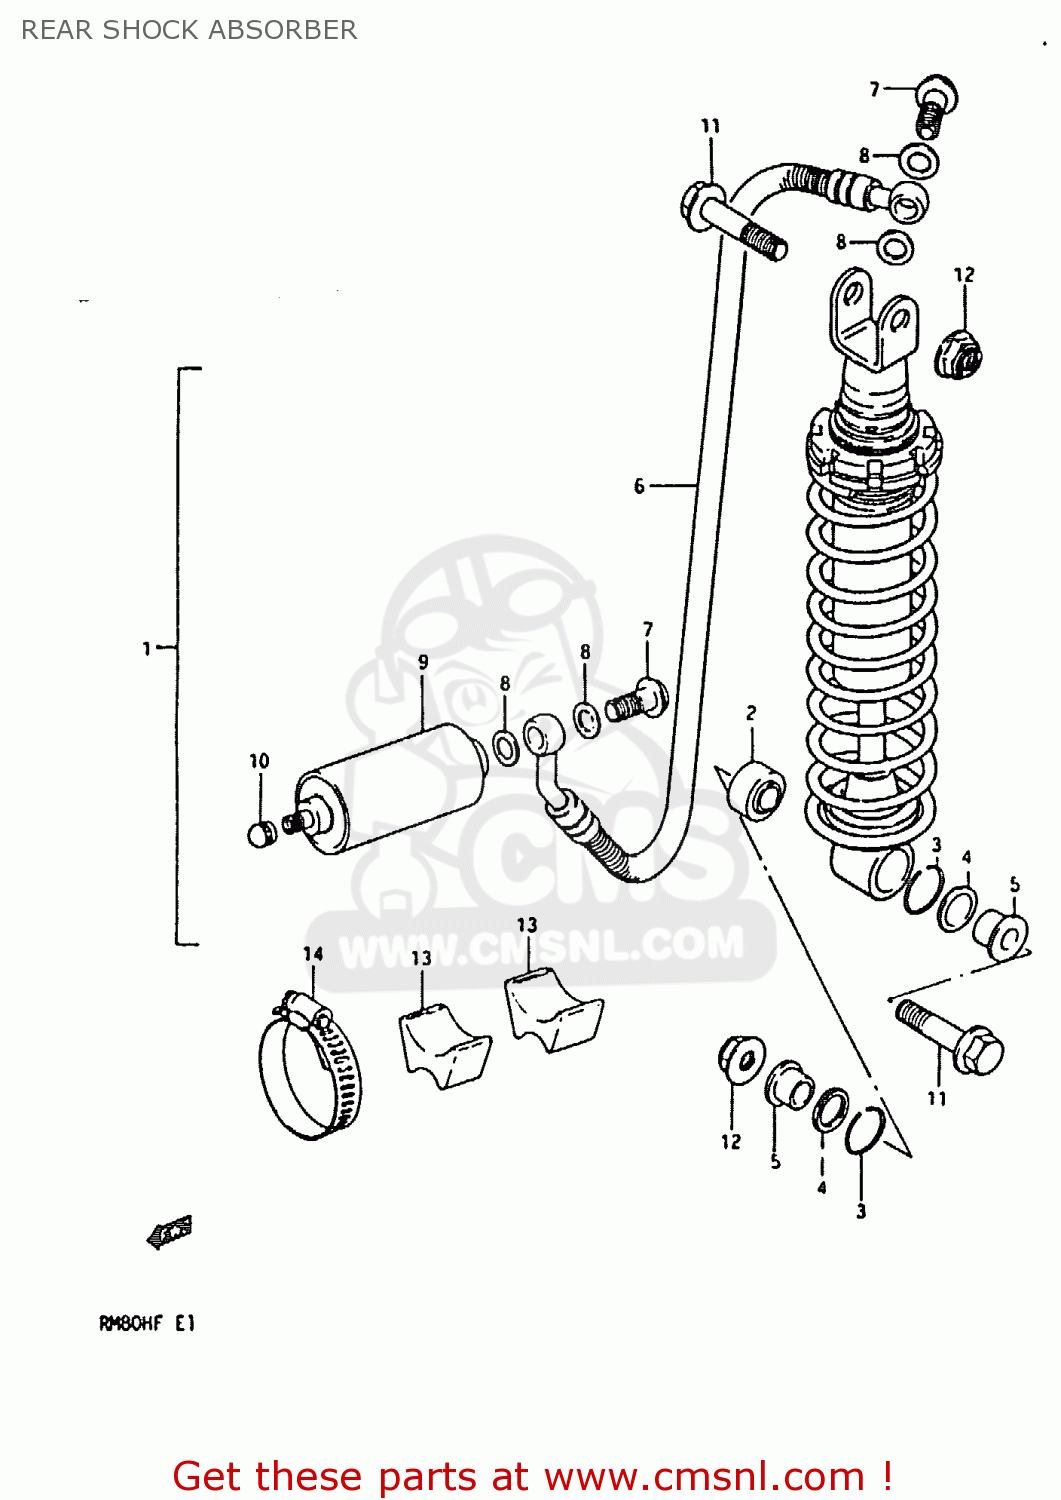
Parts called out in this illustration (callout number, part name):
1	SHOCK ABSORBER, REAR
2	BEARING,REAR SHOCK ABSORBER
3	RING
4	DUST SEAL
5	SPACER
6	HOSE,REAR SHOCK ABSORBER
7	BOLT,REAR SHOCK ABSORBER
8	WASHER(10X15X1.5)
9	RESERVE TANK,REAR SHOCK
10	CAP,VALVE AIR
11	BOLT(10X50)
12	NUT
13	CUSHION,REAR SHOCK ABSORBER
14	CLAMP
